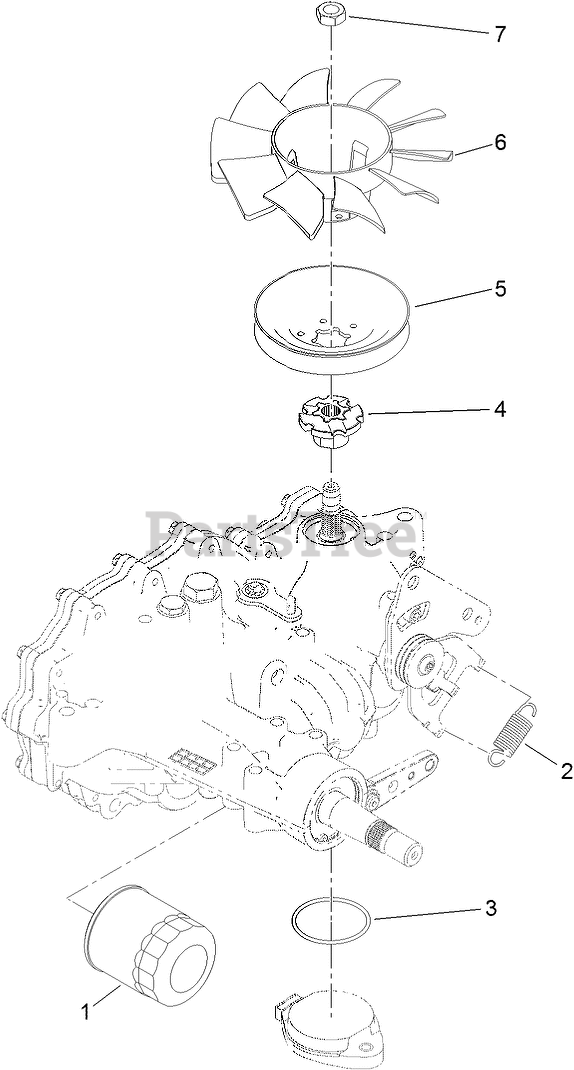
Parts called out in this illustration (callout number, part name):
1	ELEMENT-OIL FILTER, HYD
2	SPRING-EXTENSION
3	O RING-SEAL
4	HUB-PULLEY
6	FAN-7.0 INCH (10 BLADE)
